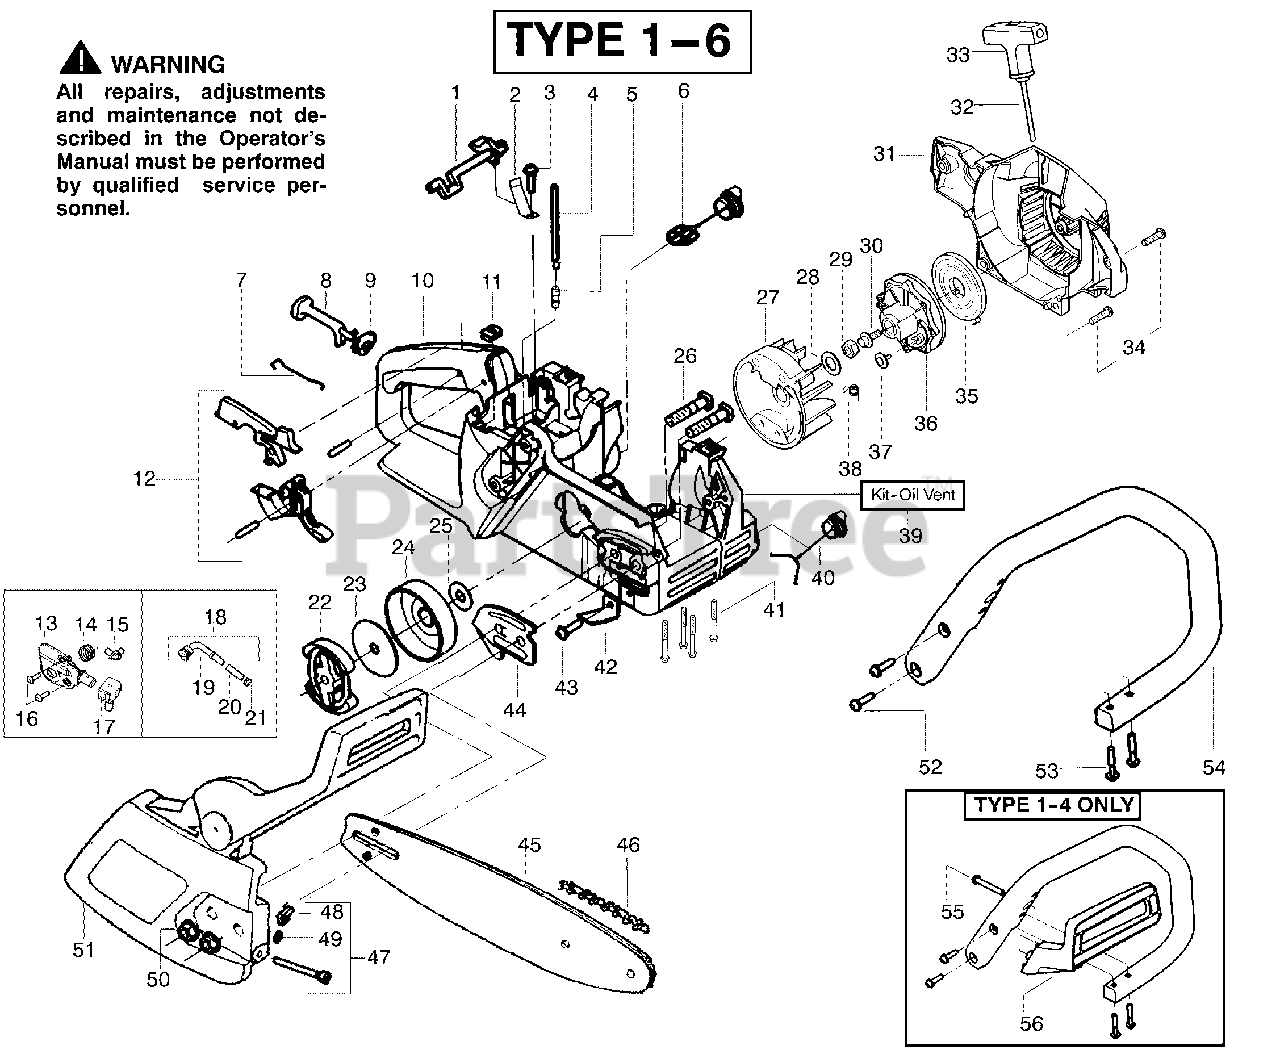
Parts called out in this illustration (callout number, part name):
1	Lever-Switch
2	Spring-Switch
4	Kit-Fuel Line (Large)
6	Assy-Fuel Cap
7	Wire-Throttle
8	Lever-Choke
9	Grommet-Choke Knob
10	Kit-Chassis Assy
11	Nut-Speed
12	Kit-Trigger & Lockout
13	Kit-Oil Pump
14	Gear-Worm Spring
15	Elbow-Oil Pickup
17	Seal Block
18	Assy-Oil-Pickup
19	Pickup-Oiler
20	Filter-Oil
21	Plug-Oil Filter
22	Assy. - Clutch
23	Washer-Clutch
24	Assy-Drum W/brg.
25	Washer - Thrust
26	Bolt-Bar Mounting
27	Assy-Flywheel
28	Washer-Flywheel
29	Nut-Flywheel
31	Housing-Fan
32	Kit-Rope
33	Handle-Starter
35	Spring-Starter
36	Pulley-Starter
38	Spring - Starter Dog
39	Kit-Oil Vent
40	Assy-Oil Cap
42	Chain Catcher
44	Plate-Bar Mounting
46	Chain-14"
47	Kit-Bar Adjust
48	Pin-Bar Adjust
49	Retainer-Bar Adjust
50	Nut-Bar Mounting
51	Assy-Chain Brake
54	Handle-Front
55	Bolt-Handguard
56	Handguard
